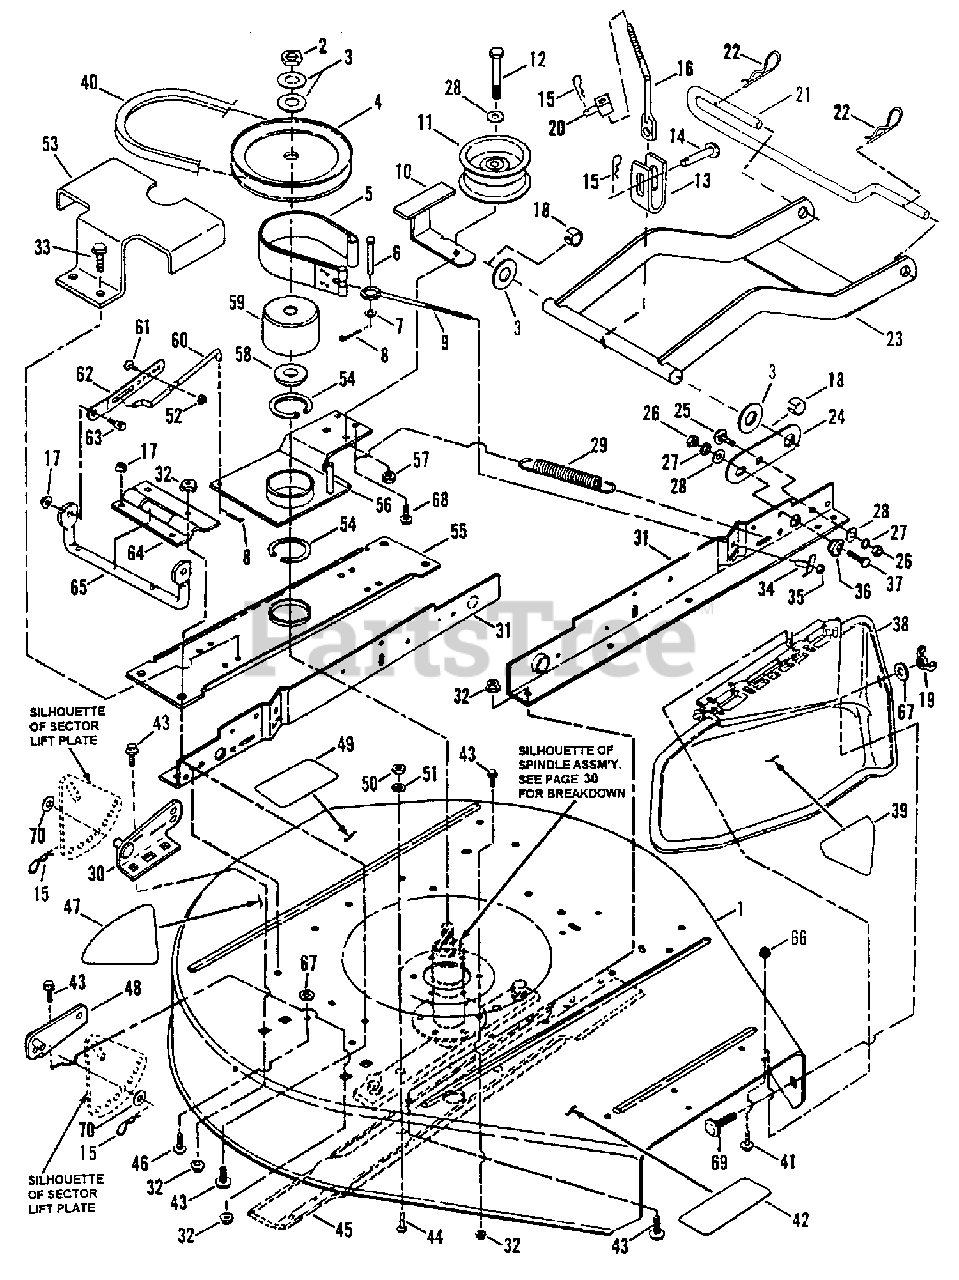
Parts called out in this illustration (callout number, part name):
1	DECK, 30" Cutting
2	NUT, 3/4-16 Hex Jam
3	WASHER, 3/4" I.D. x 1-1/2" O.D. Flat
4	PULLEY, Spindle, 6 1/2" O.D.
5	ASSEMBLY, Brake Band
6	PIN, 1/4 x 1-1/4" Clevis
7	WASHER,1/4" I.D. x 5/8" O.D. Flat
8	COTTER-PIN, 3/32 x 3/4"
9	BOLT, 1/4-20 Eye
10	GUIDE, Belt
11	PULLEY, Idler 4.0" O.D. (Flat 3.25" Running Surface)
12	SCREW, 3/8-16 x 1-3/4" Hex. Head Cap, Grade 5
13	BRACKET, Front Lift Hanger
14	PIN, 3/8 x 1-1/2" Clevis
15	HAIRPIN for 3/8" Dia.
16	ROD, Front Lift
17	NUT, 5/16-18 Hex Flange Lock, Grade 5
18	RING, Front Lift Arm
19	NUT, 5/16-18 Wing
20	SWIVEL, Brake
21	PIN, Front Deck Hanger
22	HAIRPIN, for 5/8" Dia.
23	LIFT, Front Arm
24	LINK, Adjustment
25	BOLT, 3/8-16 x 3/4" Carriage, Gr. 5
26	NUT, 3/8-16 Hex, Grade 5
27	WASHER, 3/8 Split Lock
28	WASHER, Flat, 3/8 SAE
29	SPRING, Clutch & Brake
30	BRACKET, Rear Deck Lift Left Side
31	RAIL, 30" Cutting Deck
32	NUT, 3/8-16 Hex Flange Lock
33	SCREW, 5/16-18 x 5/8" S.T.
34	T-NUT, 1/4-20 Thread
35	NUT, 1/4-20 Hex, Grade 5
36	ECCENTRIC, Leveling
37	SCREW, 3/8-16 x 1" Hex Head Cap, Grade 5
38	ASSEMBLY, Deflector
39	DECAL - DANGER (Cut Finger)
40	BELT, Drive, 30" Cutting Deck
41	BOLT, 5/16-18 x 1/2" Hex Flange Lock, Grade 5
42	DECAL - CAUTION
43	BOLT, 3/8-16 x 3/4" Hex Flange Lock, Grade 5
44	SCREW, 1/2-20 x 1" Hex Head Cap, Grade 5
45	BLADE, 30" Cutting Deck
46	BOLT, 5/16-18 x 3/4" Hex Flange Lock, Grade 5
47	DECAL, 30"
48	BRACKET, Rear Deck Lift, Right Side
49	DECAL - CAUTION, Rotating Blades
50	NUT, 1/2-20 Hex Jam
51	WASHER, 1/2 Internal Tooth Lock
52	NUT, 1/4-20 Hex Flange Lock Gr. 5
53	GUIDE, Belt
54	RING, 2" External Retaining
55	BRACE, Spindle
56	ARM, Idler
57	NUT, 3/8-16 Hex Center Lock, Gr. 5
58	WASHER, Spindle
59	DRUM, Brake
60	ROD, Link, Clutch/Brake
61	BOLT, 1/4-20 x 1/2" Hex Flange Lock, Grade 5
62	BRACKET, Link, Clutch/Brake
63	SCREW, 5/16-18 x 3/4" Shoulder
64	BRACKET, Pivot Arm
65	ARM, Pivot
66	NUT, 5/16-18 Hex Flange Lock, Grade 5
67	WASHER, 5/16 Flat
68	SCREW, 5/16-18 x 3/4" Self-Tapping
69	BOLT, 5/16-18 x 3/4" Short Neck Carriage, Grade 5
70	WASHER, 3/8" Flat
